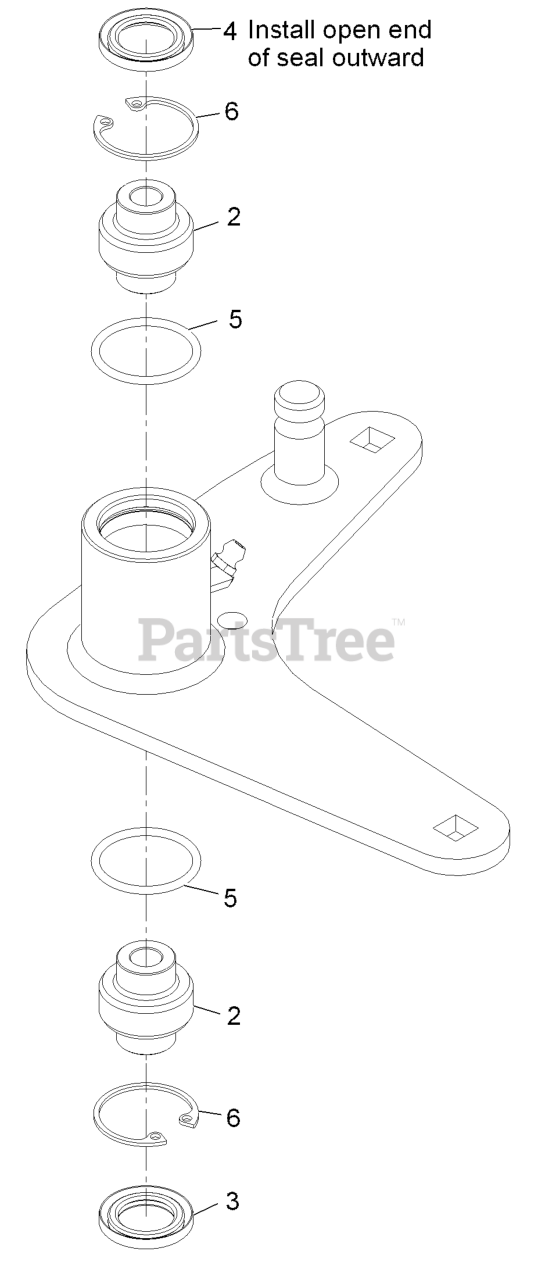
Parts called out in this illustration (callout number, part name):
2	Bearing-Spherical
3	Seal-Lip, Double
4	Seal-Single Lip
6	Ring-Retaining
